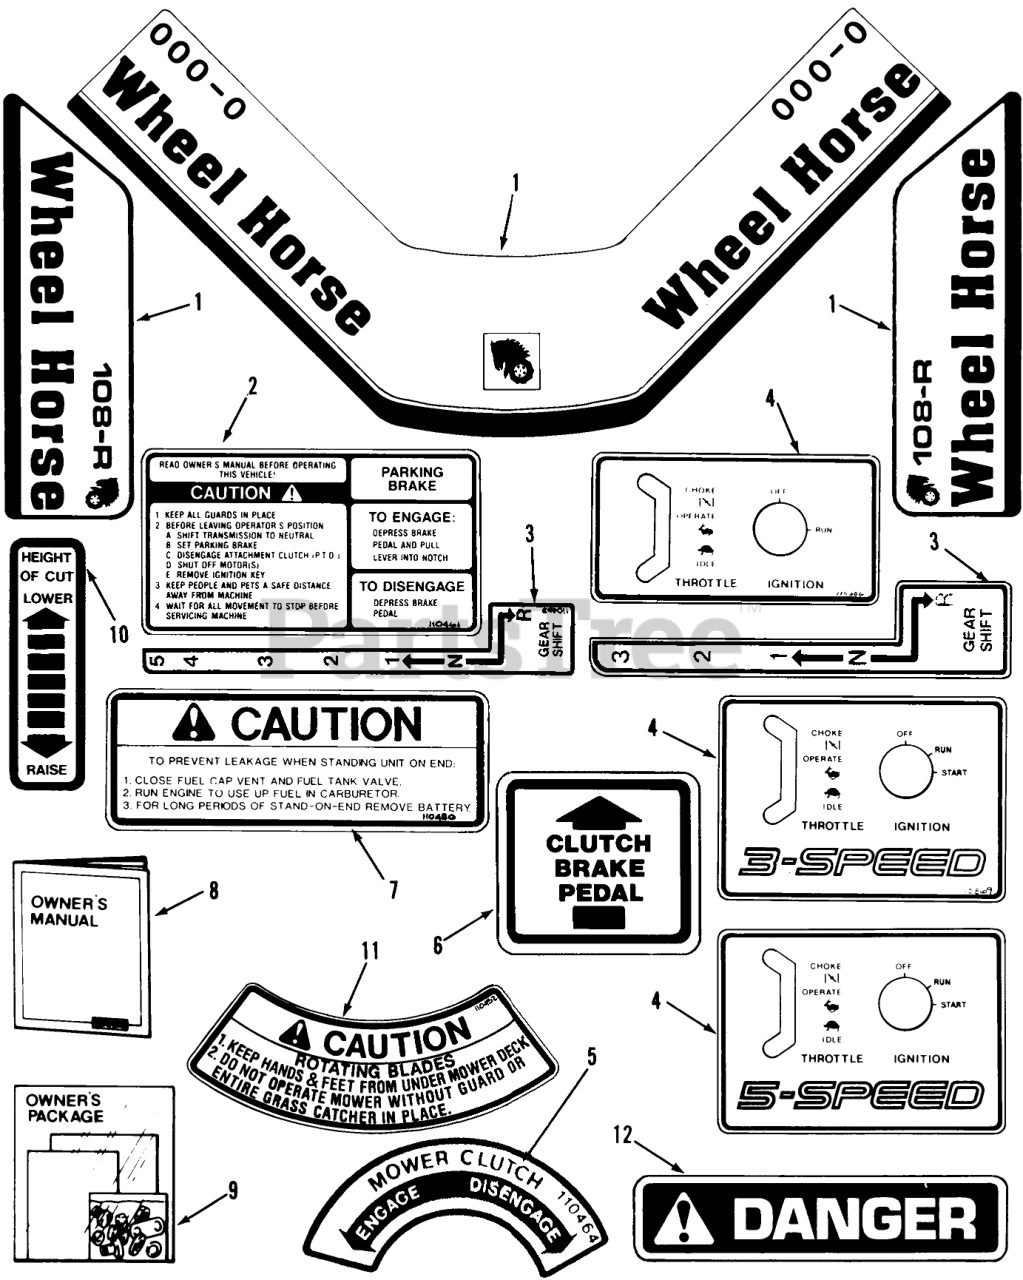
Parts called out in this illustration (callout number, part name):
1	Front Steering Shroud Decal R.H. 108-R Only
2	Cation Parking Brake Decal
3	Shift Decal 3-Speed
4	DECAL IGN & THROTTLE
5	DECAL MOWER CLUTCH
6	DECAL B&C PEDAL
7	Fuel Tank Caution Decal
8	Owners Manual
9	Loose Parts Package 108-R Only
10	Mower Height Adjustment Decal
11	Mower Rotating Blades Decal
12	Danger Decal
13	5-Speed Decal
